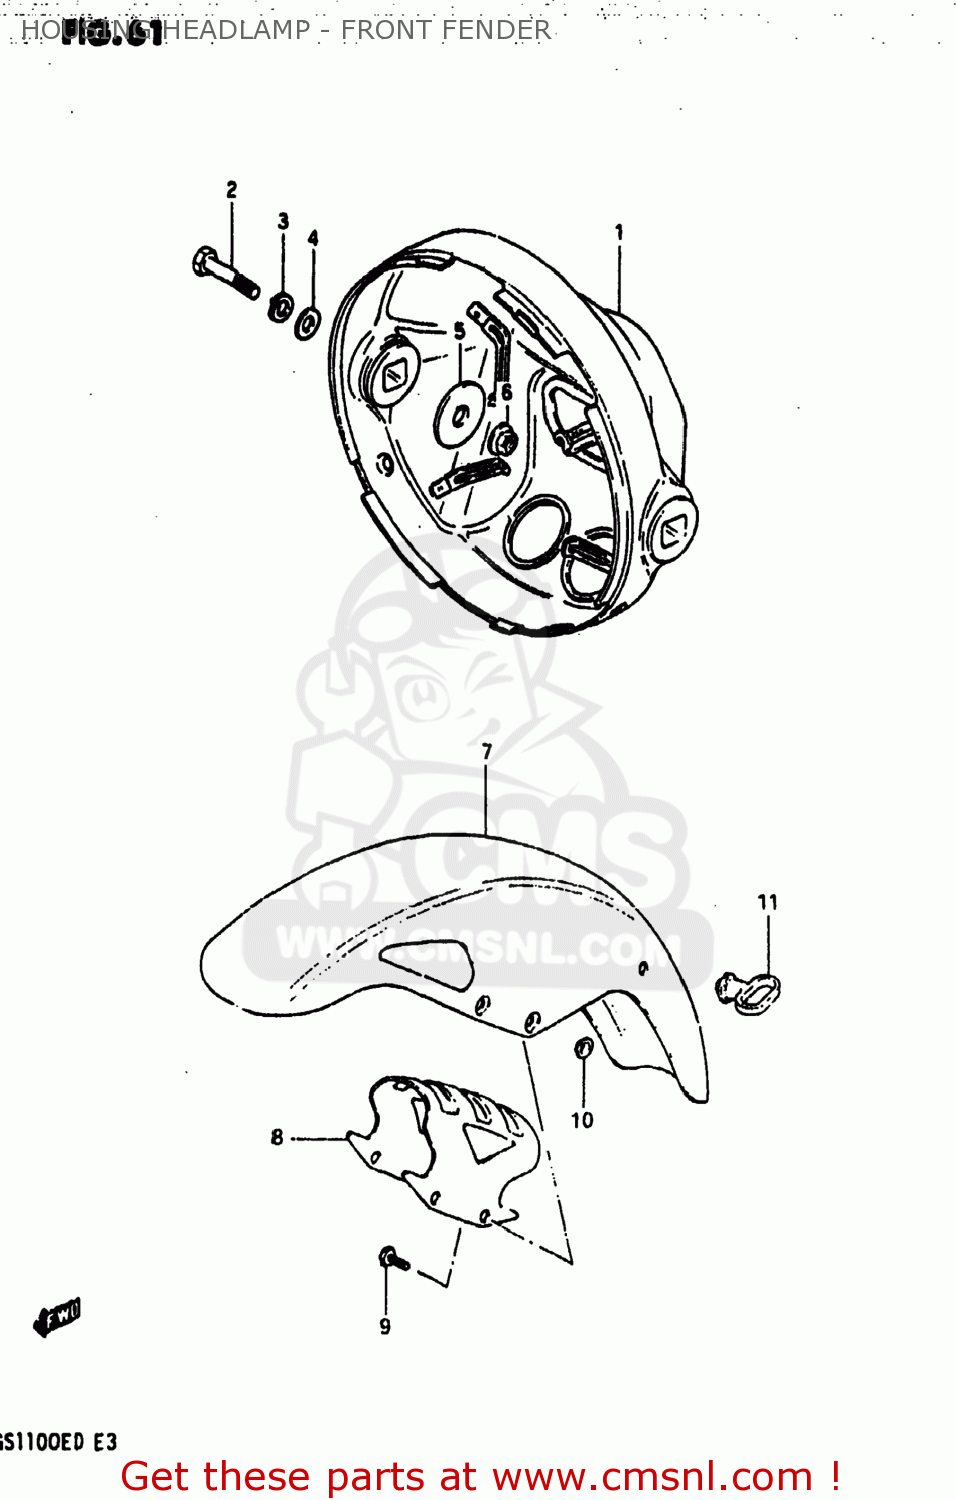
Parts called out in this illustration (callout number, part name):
1	HOUSING,HEADLAMP
2	BOLT
3	LOCK WASHER
4	WASHER
5	WASHER (8.5X29X1.6)
6	NUT
7	FENDER,FRONT
8	BRACE,FRONT FENDER
9	BOLT 8X16
10	WASHER
11	GUIDE,CABLE
